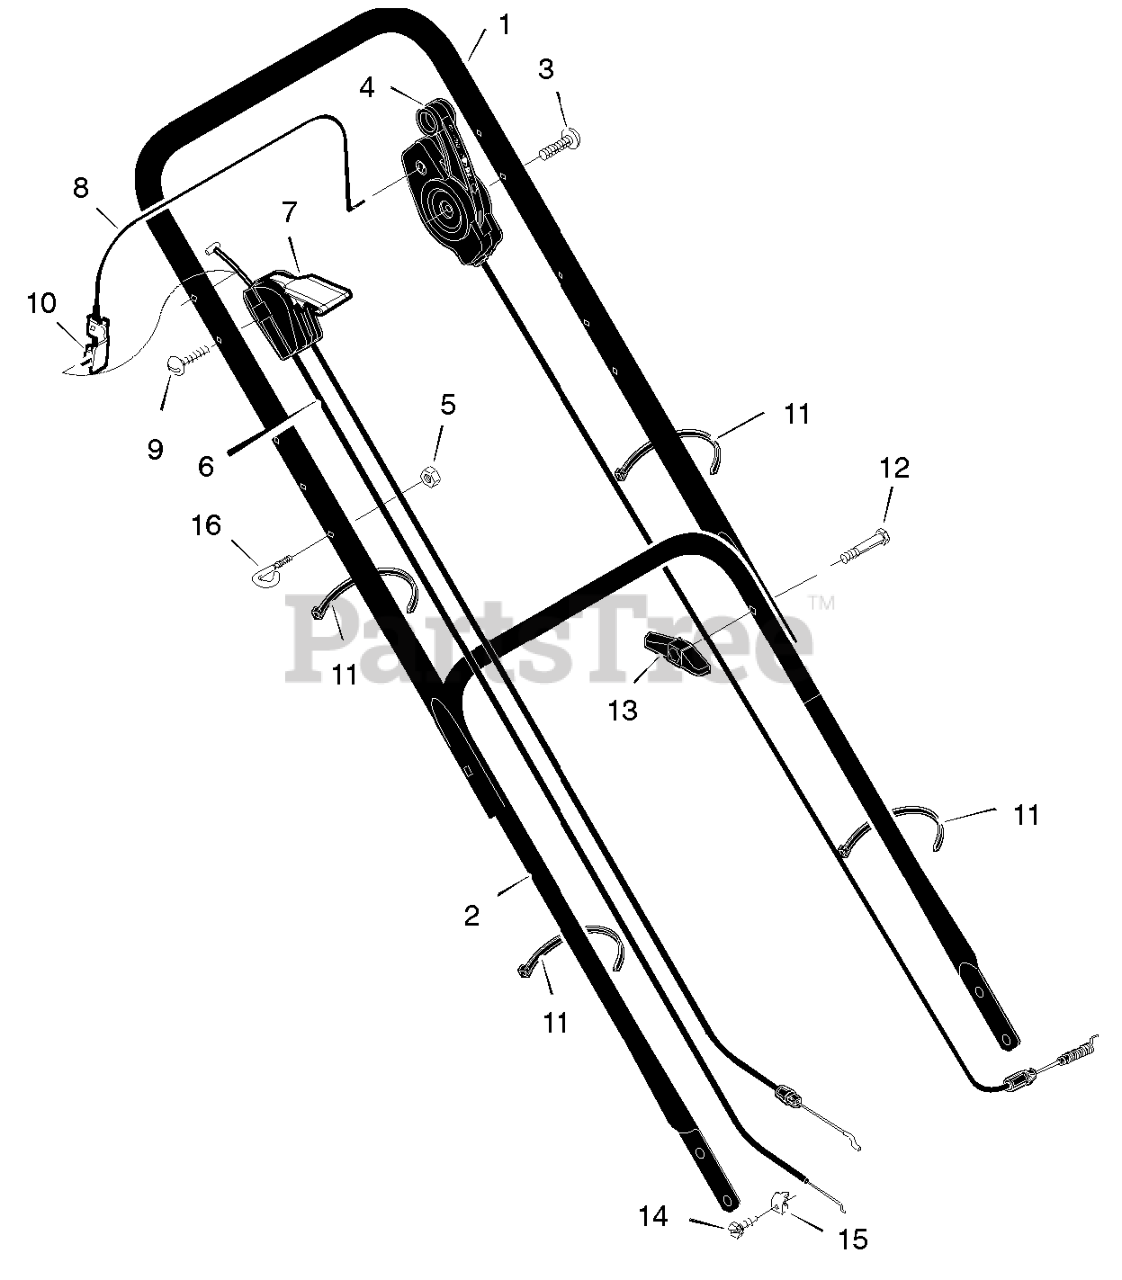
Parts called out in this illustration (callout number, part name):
1	Handle, Upper (Black)
2	Handle, Lower (Black)
4	Control, Drive
5	Locknut
6	Cable, Stop
7	Throttle Control
8	Lever, Stop
10	Bracket, Stop Lever
11	Fastener, Cable
13	Knob
16	Guide, Rope
